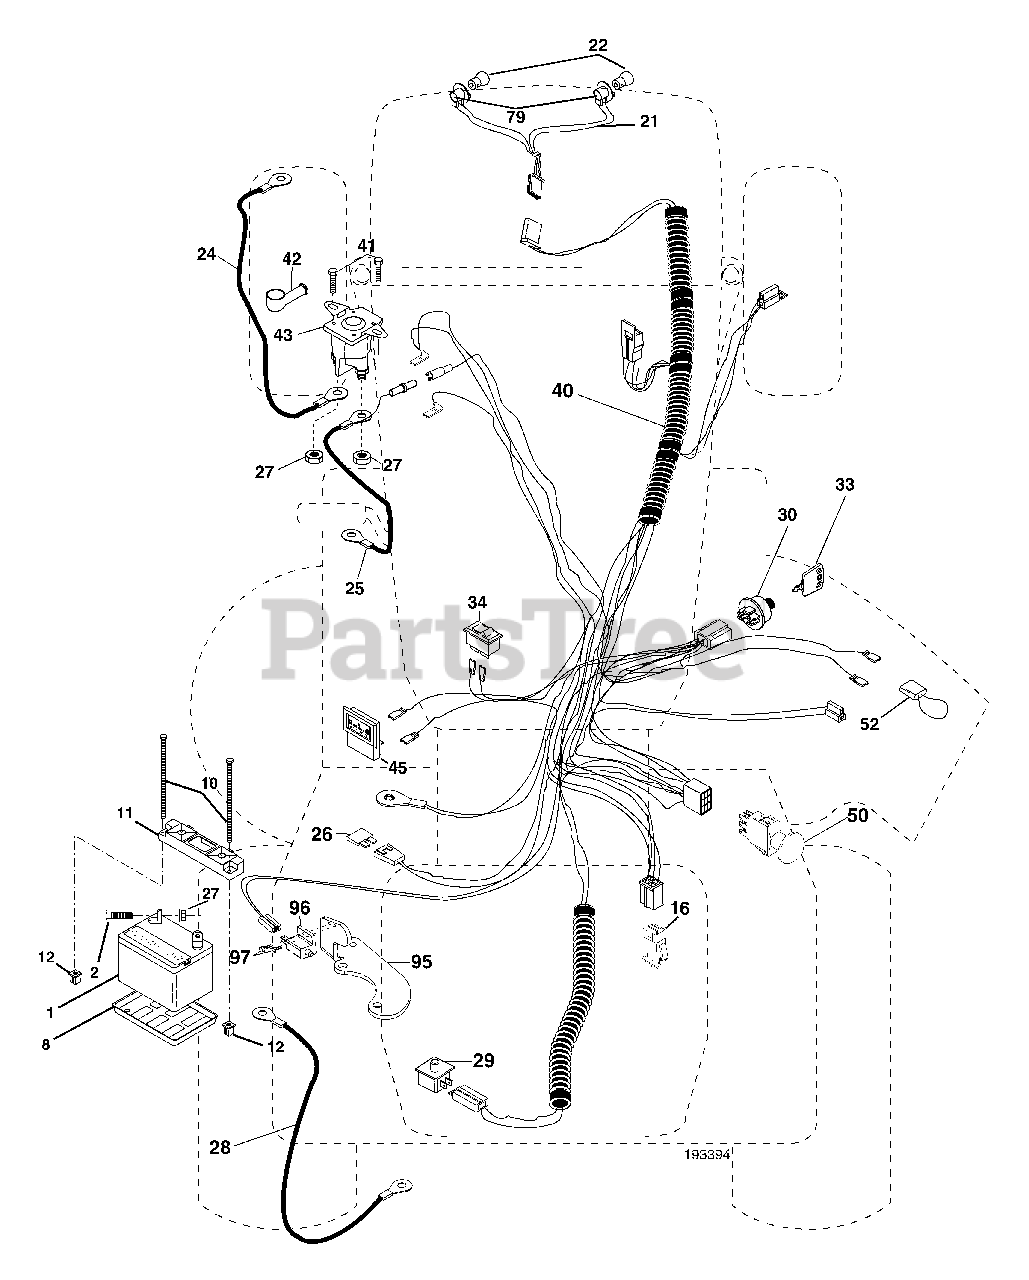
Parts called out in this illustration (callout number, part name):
1	Battery
2	Bolt Hex Head 1/4-20 x 3/4
8	Tray, Battery
10	Bolt, Battery Front 1/4-20 x 7.5 Zinc
11	Holddown Battery Front Mount
12	Nut, Push Nylon 1.4" Battery Front
16	Switch Interlock
21	Harness Socket Light w/4152J
22	Bulb Light
24	Cable Starter
25	Cable, Battery
27	Nut Keps Hex 1/4-20
28	Cable, Ground
29	Switch, Plunger
30	Switch, Ign
34	Switch Light/Reset
40	Harness Ign.
41	Screw Thd Cut 1/4-20 x 1/2
42	Cover, Terminal Red
43	Solenoid
50	Switch, PTO
52	Protection Wire Loop
79	Bulbholder Asm
95	Bracket ROS
96	Switch Intek
